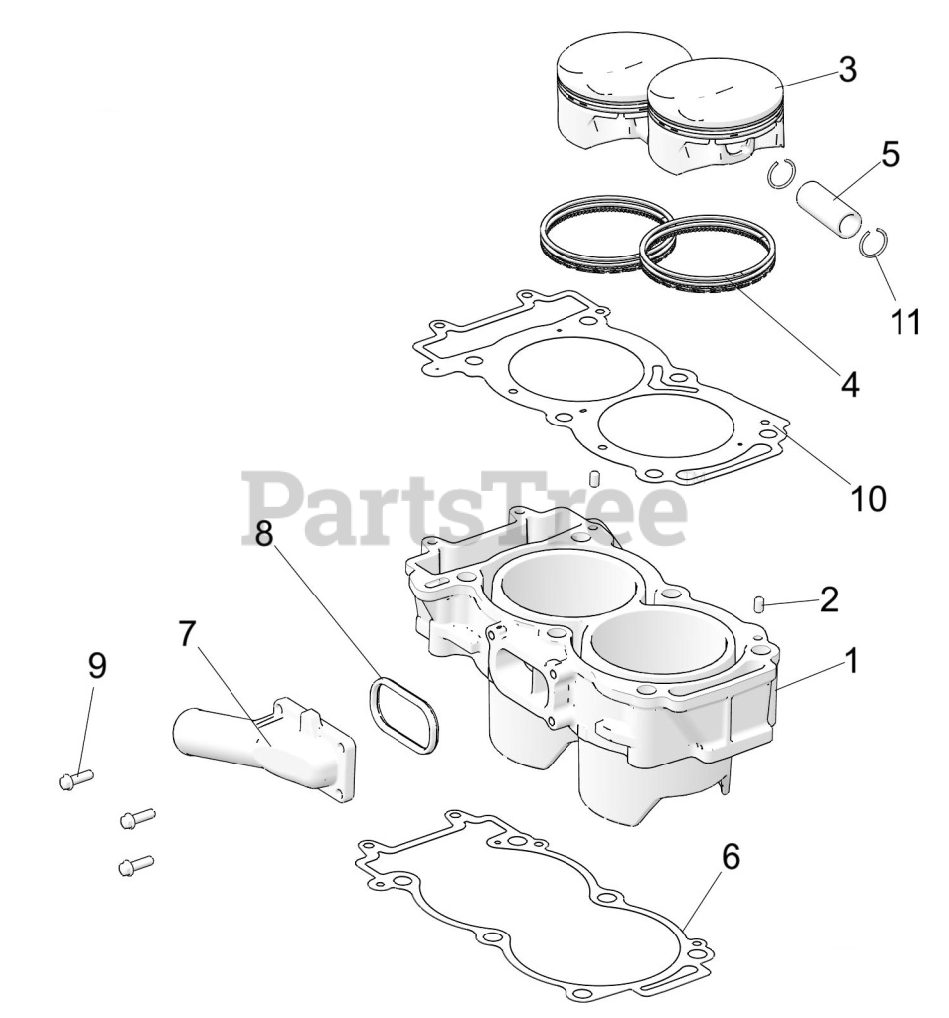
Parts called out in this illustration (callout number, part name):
1	ASM-CYLINDER-875
2	PIN-DOWEL-M6X10
3	ASM-PISTON
4	KIT, PISTON RINGS
5	PIN-PISTON
6	GASKET-BASE-2 CYL-G-90
6	GASKET, BASE, 2 CYL
7	COVER-WATER INLET-CAST
8	GASKET-WATER-INLET
9	SCR-M6X20-HXFLG-0600214
10	GASKET-CYLINDER- HEAD
11	RING-RTG-ROUNG-20.0X1.6
